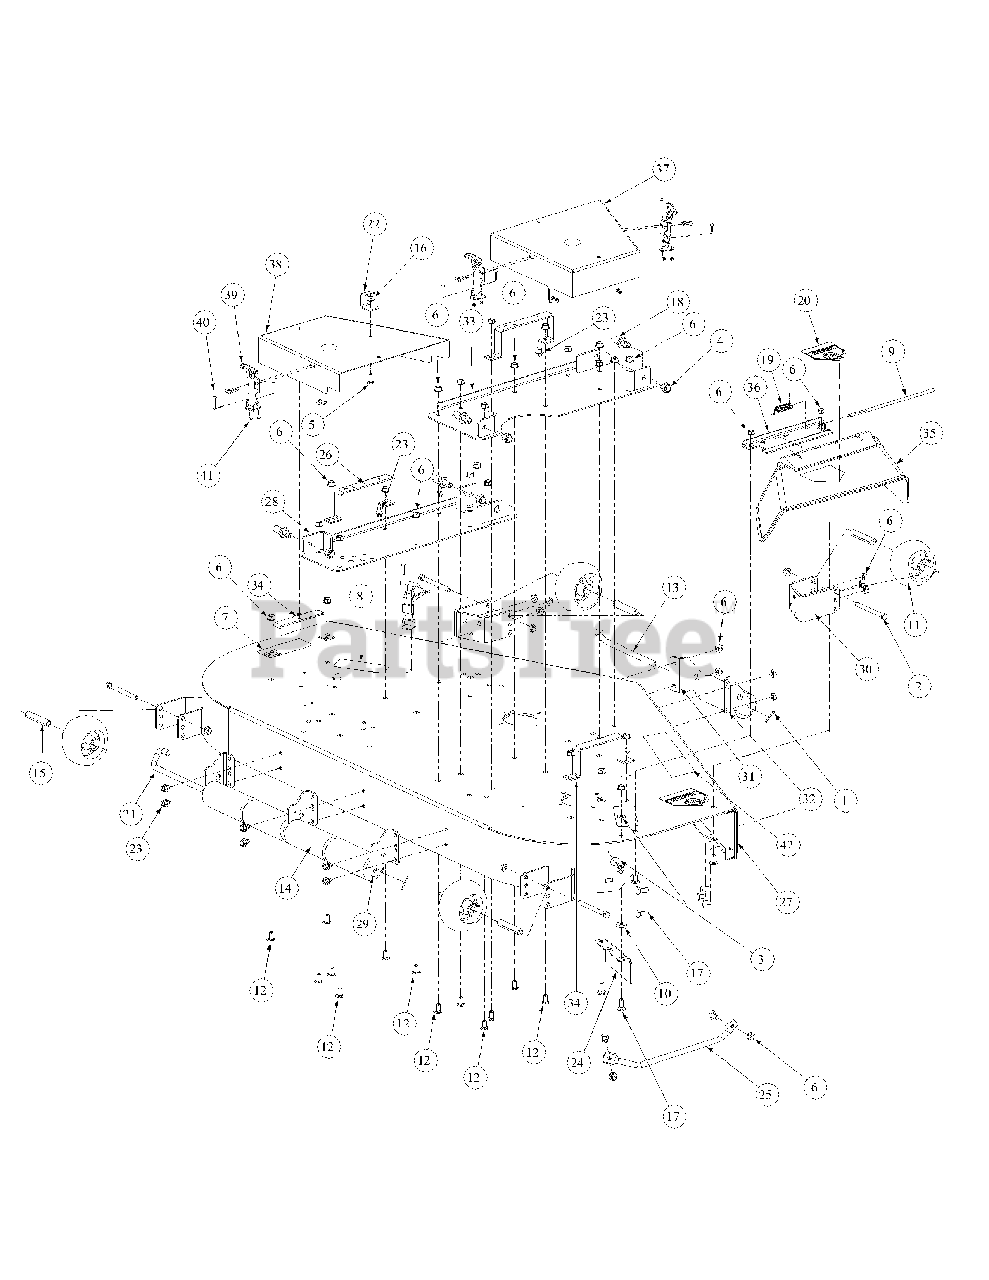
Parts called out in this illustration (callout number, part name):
1	Cotter Pin, .125 Dia. x 1.0
2	Hex Cap Screw, 3/8-16, 3.75
3	Flat Washer, 3/8
4	Lock Nut, Nylon Insert, 1/2-13
5	Hex Cap Screw, 5/16-18 x 3/4
6	Flange Lock Hex Nut, 3/8-16
7	Decal, Rotating Blade
8	Decal, Warning Shield Missing
9	Chute Deflector Rod
10	Idler Washer
11	Complete Wheel, 5.00 Dia.
12	Carriage Bolt, 3/8-16 x .75 Lg.
13	Roller Pin, 1/2 Dia. x 7.31 Lg.
14	Front Roller
15	Wheel Spacer
16	Hex Flange Lock Nut, 5/16-18
17	Carriage Bolt, 3/8-16 x 1
18	Pin, 5/8 Dia. x 1.2 Lg.
19	Torsion Spring, 0.4 ID x 2.16 Lg
20	Decal, Danger Hand and Feet
21	Roller Pin
22	Tension Rod Stop Bracket
23	Hex Index Washer Screw, 3/8-16, .5
24	Chute Bracket
25	Finger Guard
26	Belt Cover Support
27	60 Deck Assembly
28	Left Hand Mount Deck Bracket Assembly
29	Deck Roller Mount Bracket
30	Anti-Scalp Wheel Front Mount Bracket
33	Right Hand Deck Bracket Assembly
34	Outer Belt Cover Support Assembly
35	Chute Deflector
36	Chute Deflector Bracket
37	Right Hand Deck Belt Cover Weldment
38	Left Hand Deck Belt Cover Weldment
39	T-Handle Latch Draw
40	Phillips Head Screw, 10-32
41	Lock Nut, Nylon Insert, 10-32
42	Commercial Mower Label
